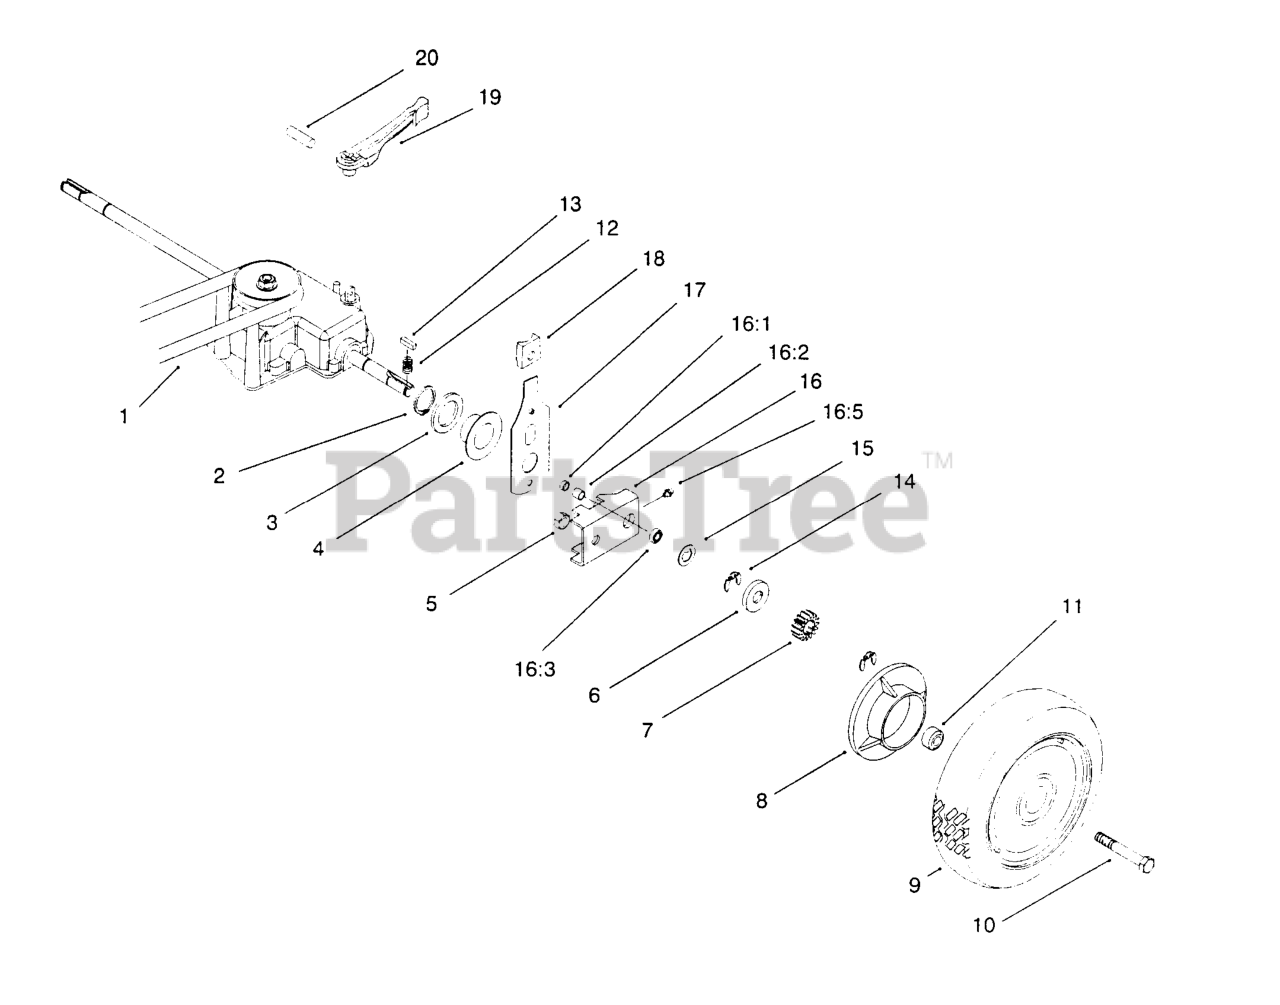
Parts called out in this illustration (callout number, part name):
1	V-BELT
2	RING-RETAINING
4	CAP-END
5	NUT-LOCK, CONE
6	WASHER-THRUST, OUTER
7	GEAR-PINION
8	COVER-WHEEL
10	SCREW-HH
11	SPACER-COVER, WHEEL
12	SPRING-COMPRESSION
14	RING-RETAINING
15	WASHER-THRUST, OUTER
16	PIVOT ARM ASM
16:1	SEAL-OIL
16:3	BEARING-WHEEL
17	REAR SPRING ARM ASM
18	KNOB-ARM
19	LEVER-SHIFT
20	PIN-SPRING
